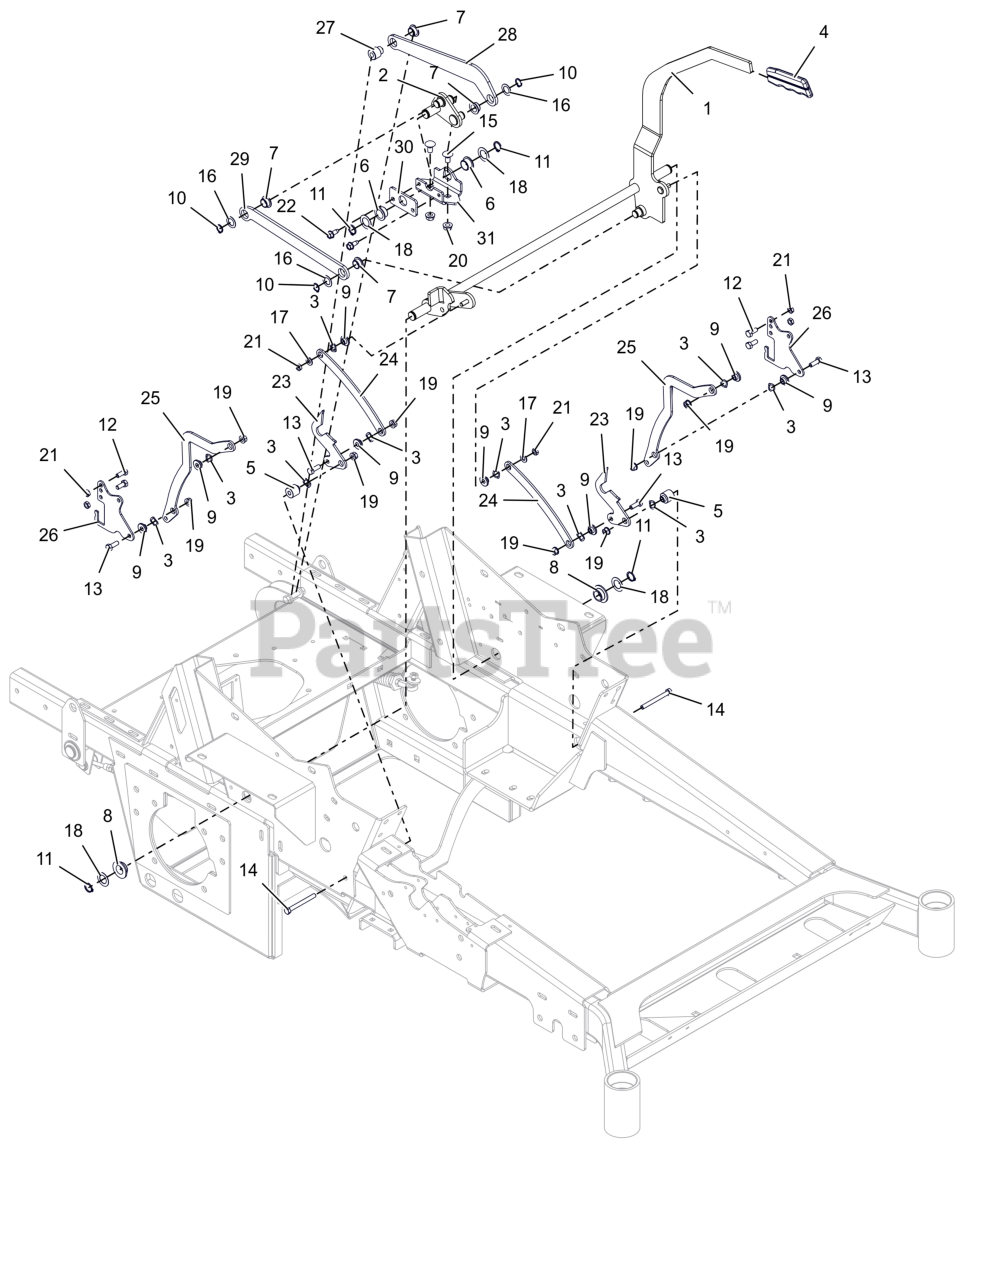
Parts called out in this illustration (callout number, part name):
1	WLDMT, PARKING BRAKE ARM (BLACK)
2	WLDMT, BRAKE ACTIVATION PIVOT
3	WAVE WASHER .531X.781X.125FH
4	GRIP, PARKING (GRAY)
5	BUSHING FLANGED - .318X.500X.972X.875
6	BSHG, FLANGE .750 X .875 X .5000 X 1.125
7	BSHG, FLANGE .625 X .750 X .375 X 1.000
8	BSHG, FLANGED .762 X 1.48 X .44 IGLIDER
9	BSHG-FLG .32X.500X.344X.880
10	RG-RTNG-EXT .625X.050
11	RG-RTNG-EXT .689X.078
12	BLT,HEX .31-18X.75 G5 ZCC
13	BLT, HEX .31-18X.875 G5 ZCC
14	BLT, HEX .31-18X3.00 G5 ZCC
15	BLT, RHSN .38-16X.750 G5 ZCC
16	WSHR-THRST .625 X 1.0 X .03
17	WSHR,FLT .344X.688X.065 ZCC
18	WSHR-HDND-THRST .758X1.23X.031
19	NUT,LK-CTR-FLG .31-18 GF ZCC
20	NUT-LK-CTR-FLG .375-16 GF ZCC
21	NUT-LK-CTR-JAM .312-18 GB ZCC
22	SCR,TAP .312-18X.75 HWH TR ZCC
23	BRKT, BRAKE - RTN (BLACK)
24	BRKT, LINK - BREAK RTN (BLACK)
25	BRKT, LINK - SPEED CONTROL HTG
26	BRKT, SPEED - HTG (BLACK)
28	LINK, BRAKE ACTIVATION REAR
29	LINK, BRAKE ACTIVATING FRONT
30	PLATE, BSHG MOUNTING
31	BRKT, BSHG MTG
